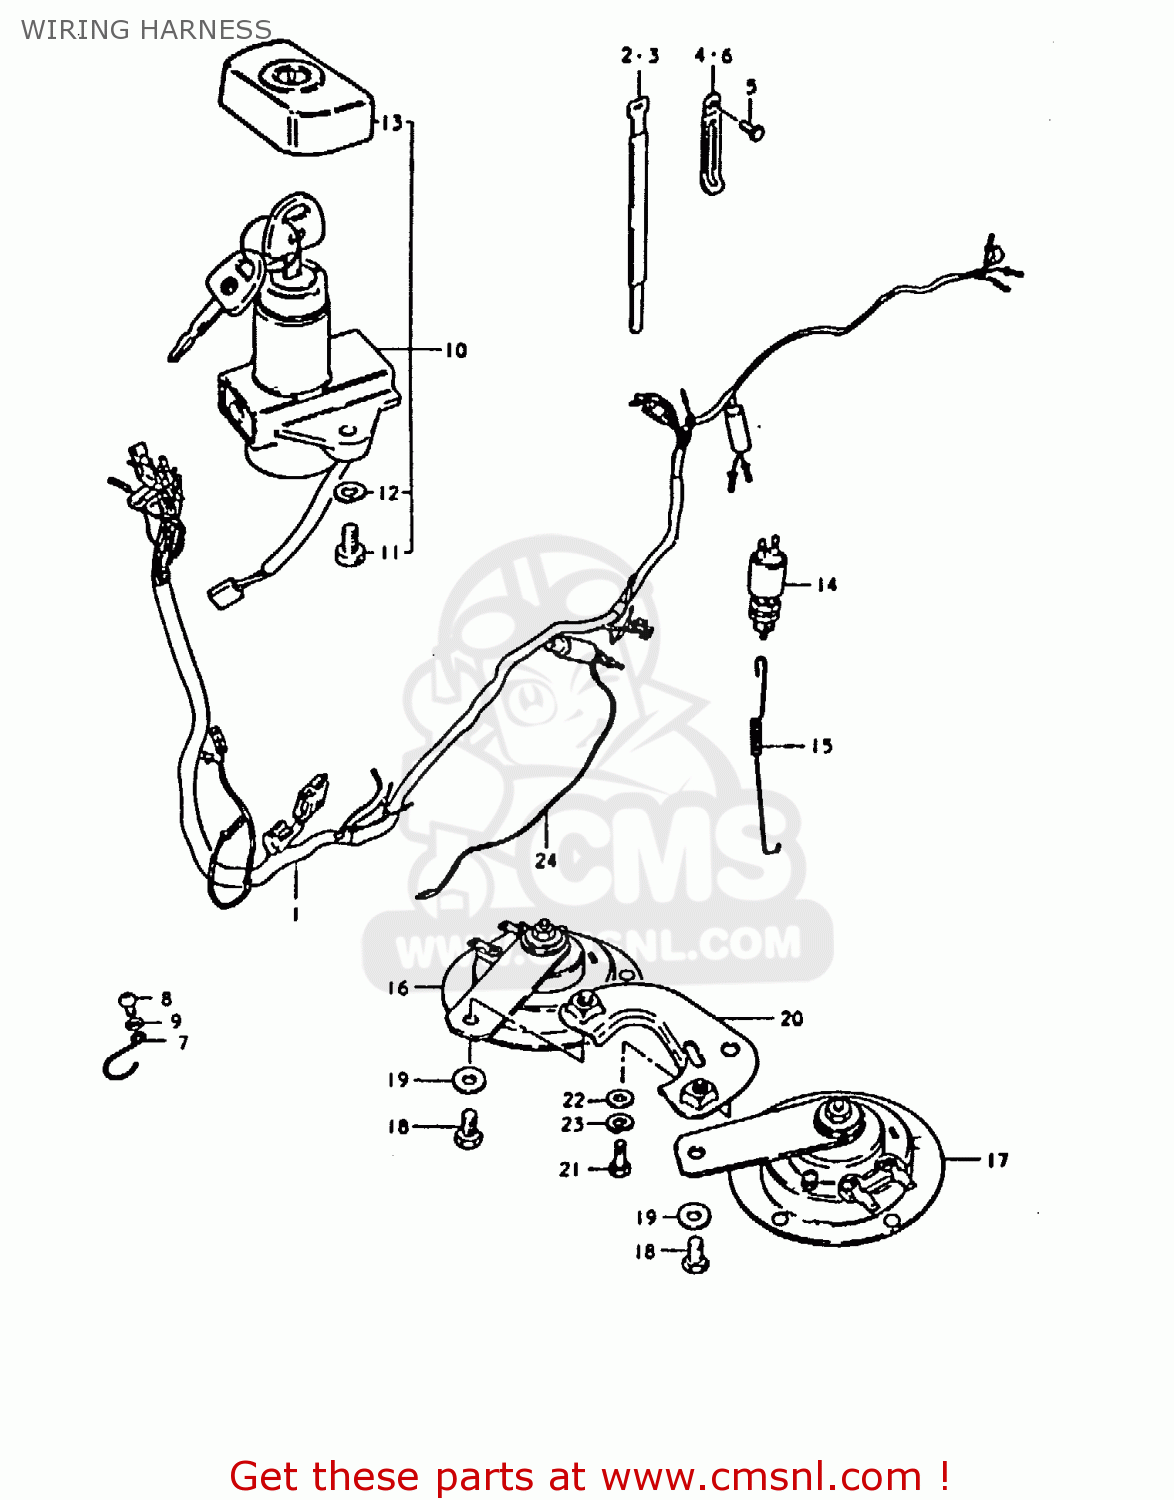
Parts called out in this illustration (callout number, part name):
1	HARNESS,WIRING
2	CLAMP(L:120)
3	CLAMP
4	CLAMP
5	BOLT
6	CLAMP
7	GUIDE,WIRING HARNESS
8	SCREW 6X12
9	WASHER 6MM
10	LOCK ASSEMBLY,STEERING
11	BOLT
12	LOCK WASHER
13	CAP,IGNITION SWITCH
14	SWITCH ASSY,BRAKE LAMP
15	SPRING
16	HORN ASSEMBLY,LOW PITCH
17	HORN ASSEMBLY,HIGH PITCH
18	BOLT 8X12
19	WASHER
20	BRACKET,HORN
21	BOLT
22	WASHER
23	LOCK WASHER
24	WIRE
